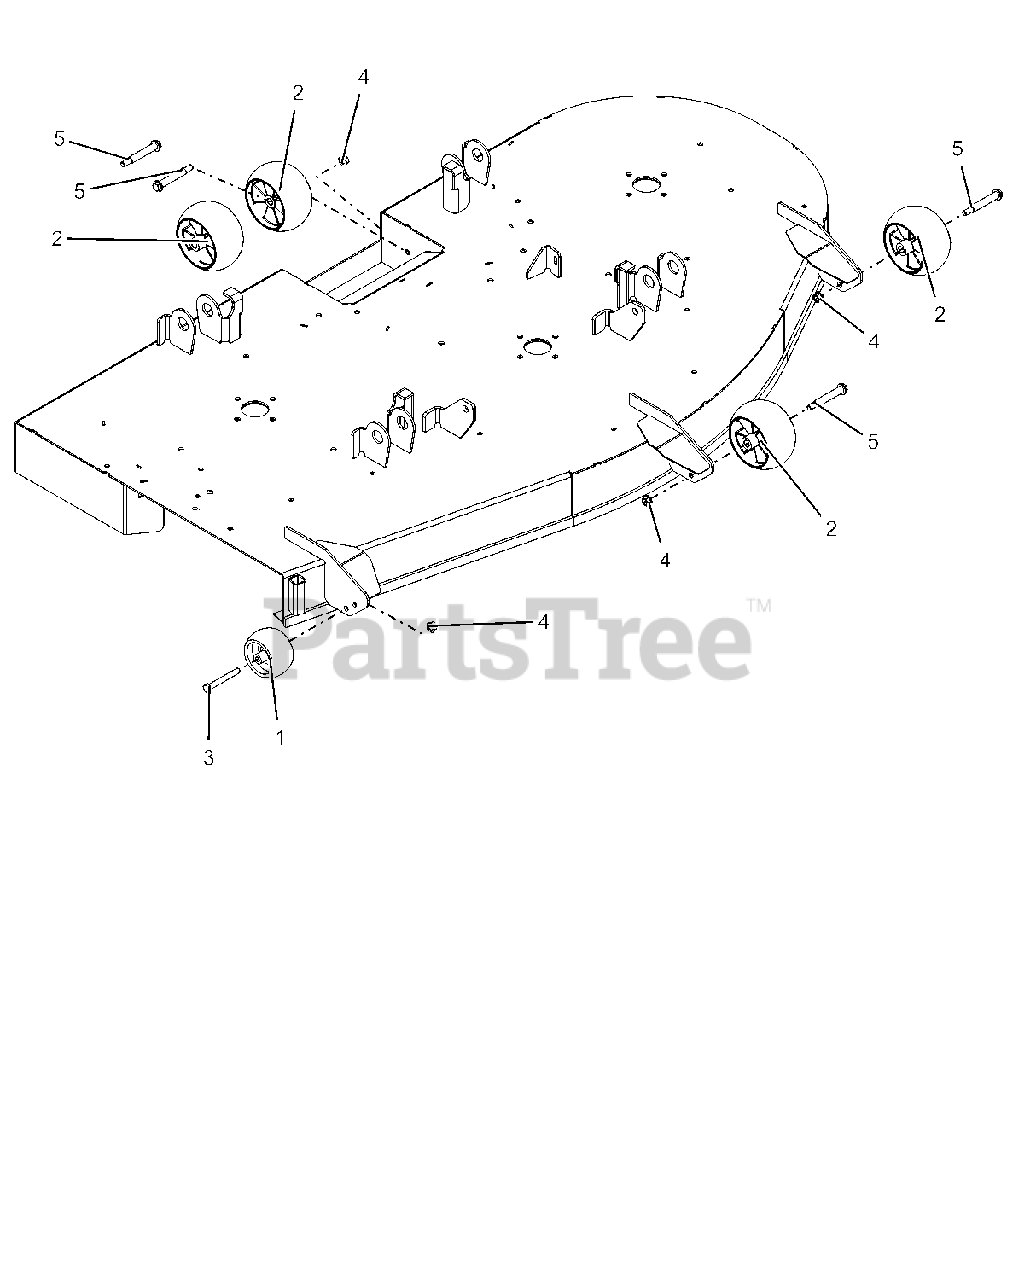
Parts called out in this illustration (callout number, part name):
2	ANTI-SCALP WHEEL - 5XOS
3	BLT-HEX .38-16X3.00 GR8 YWZC
4	NUT, LK-TOP-FLG .38-16 YWZC
5	BLT-SHLDR .38-16X2.50 HWH G5YZ
